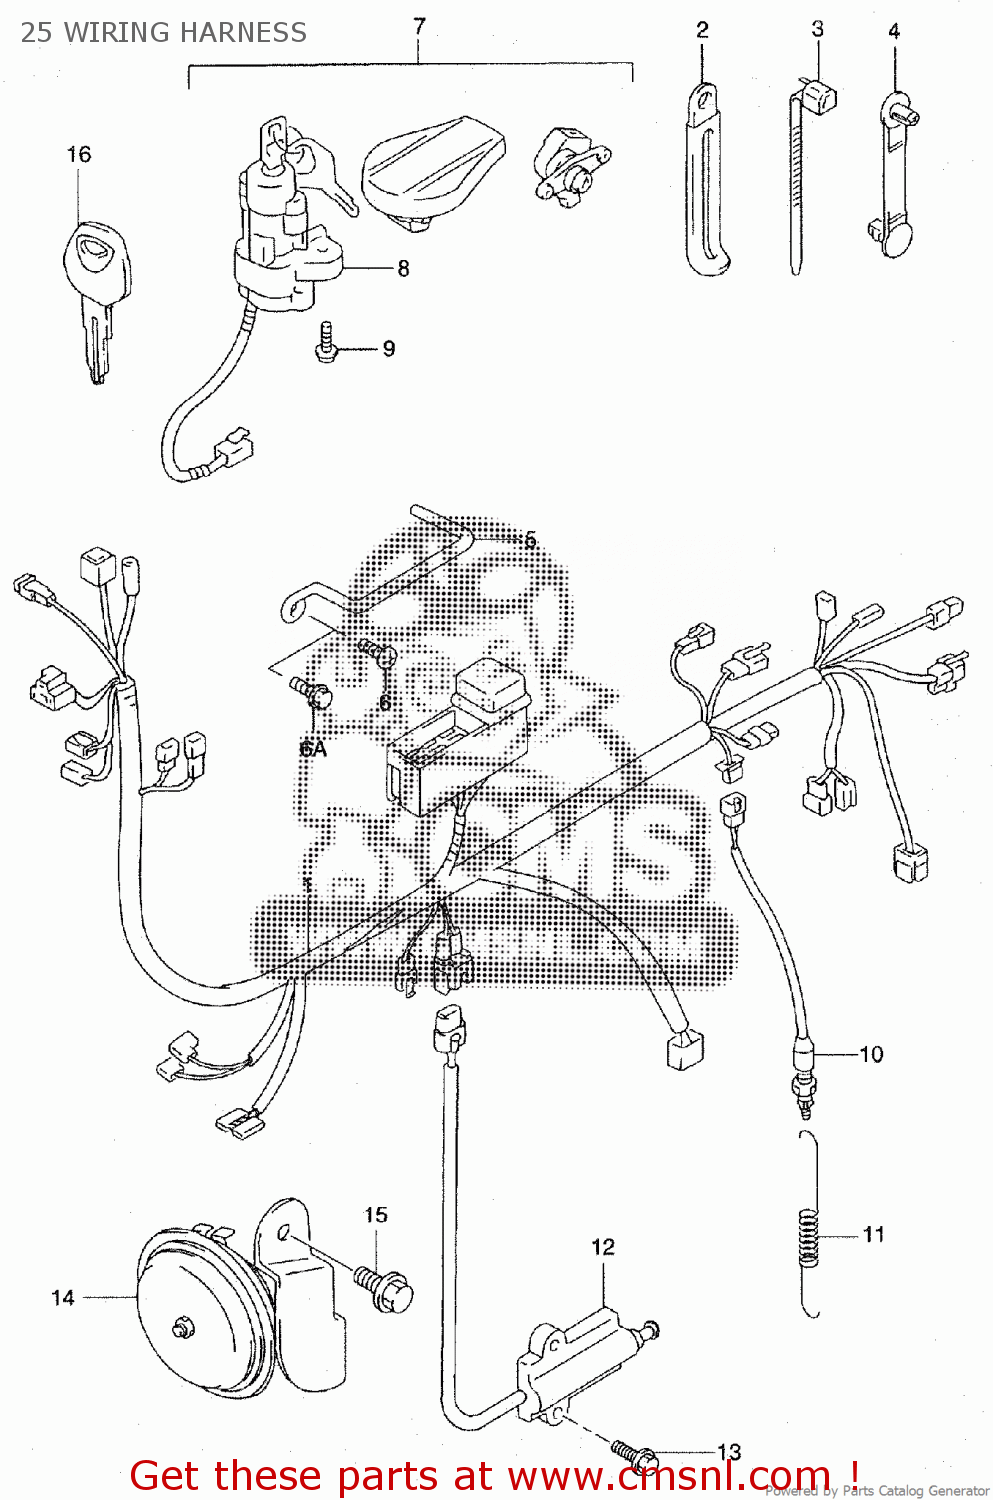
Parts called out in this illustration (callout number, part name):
2	CLAMP(L:65)
3	CLAMP(L:125)
4	CLAMP(L:33)
6	SCREW 6X12
6A	BOLT
8	LOCK ASSY,STEERING
9	BOLT(8X20)
10	SWITCH ASSY,STOP LAMP
11	SPRING
12	SWITCH ASSY,SIDE STAND
13	BOLT
15	BOLT
16	KEY,BLANK
